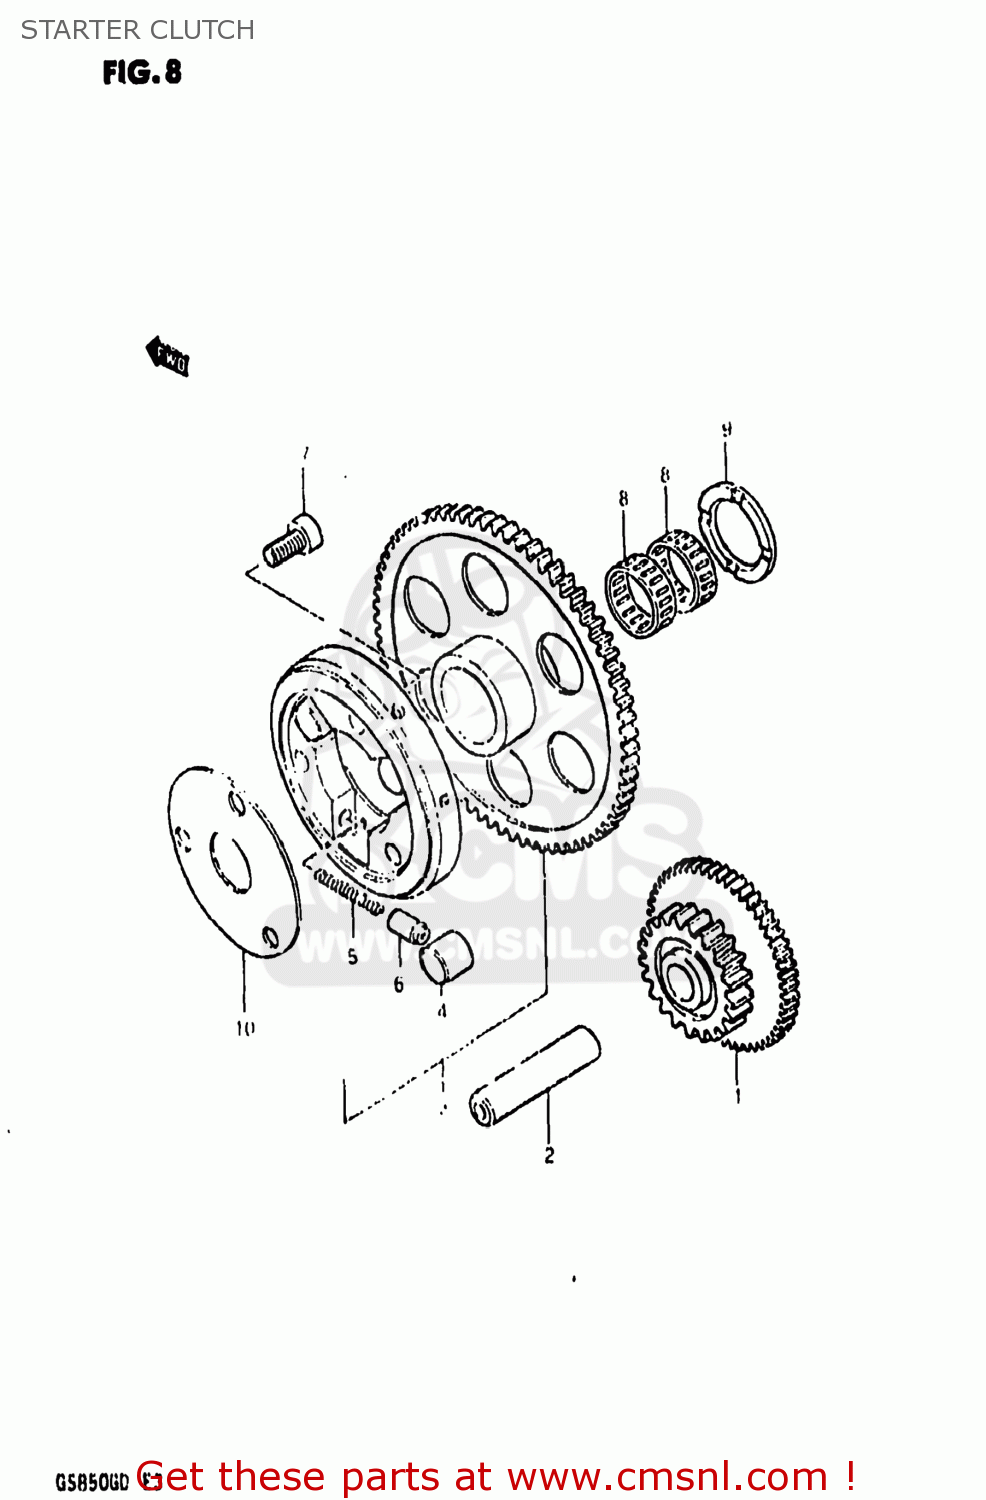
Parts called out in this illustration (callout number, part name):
1	GEAR,STARTER IDLE
2	PIN(7.4X13X61)
3	CLUTCH SET,STARTER
4	ROLLER(15X13)
5	SPRING
6	PIECE,PUSH
7	BOLT
8	BEARING(25X29X9.9)
9	WASHER(25X38X2.5)
10	SHIM,STARTER CLUTCH HUB
